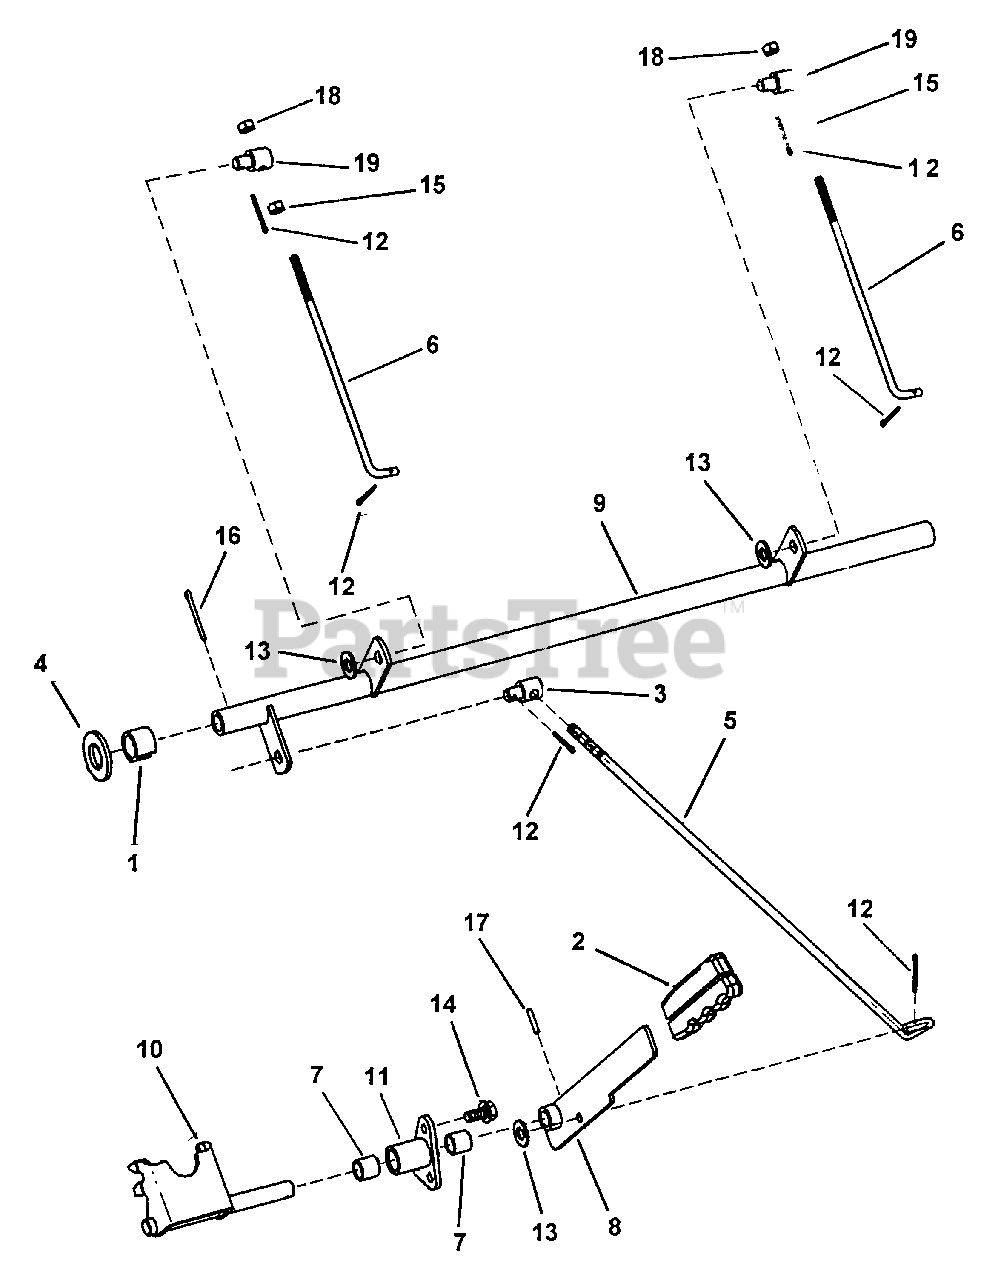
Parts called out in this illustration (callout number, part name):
1	RING, Rear Lift Arm
2	GRIP, Flat Bar
3	SWIVEL, Adjustable (5/16-18 thread)
4	WASHER, 3/4 I.D. x 1-1/2 O.D. x 9/64" Flat
5	ARM, Brake Lift (3/8-24 thread)
6	ROD, Hydrostatic Brake (1/4-28 thread)
7	SLEEVE Bearing, 1/2 I.D. x .629
8	ARM, Parking Brake
9	SHAFT, Brake
10	BRACKET, Joystick Lockout
11	PLATE, Support
12	COTTER PIN, 3/32 x 1"
13	WASHER, 3/8" Flat
14	SCREW, 5/16-18 x 5/8" Hex Washer Face Self-Tap
15	HN, 1/4F GR5 YZ
16	COTTER PIN, 1/8 x 1-1/4"
17	PIN, Roll 1/8 x 3/4"
18	NUT, 1/4-28 Hex Nyloc
19	SWIVEL, 1/4" Smooth
